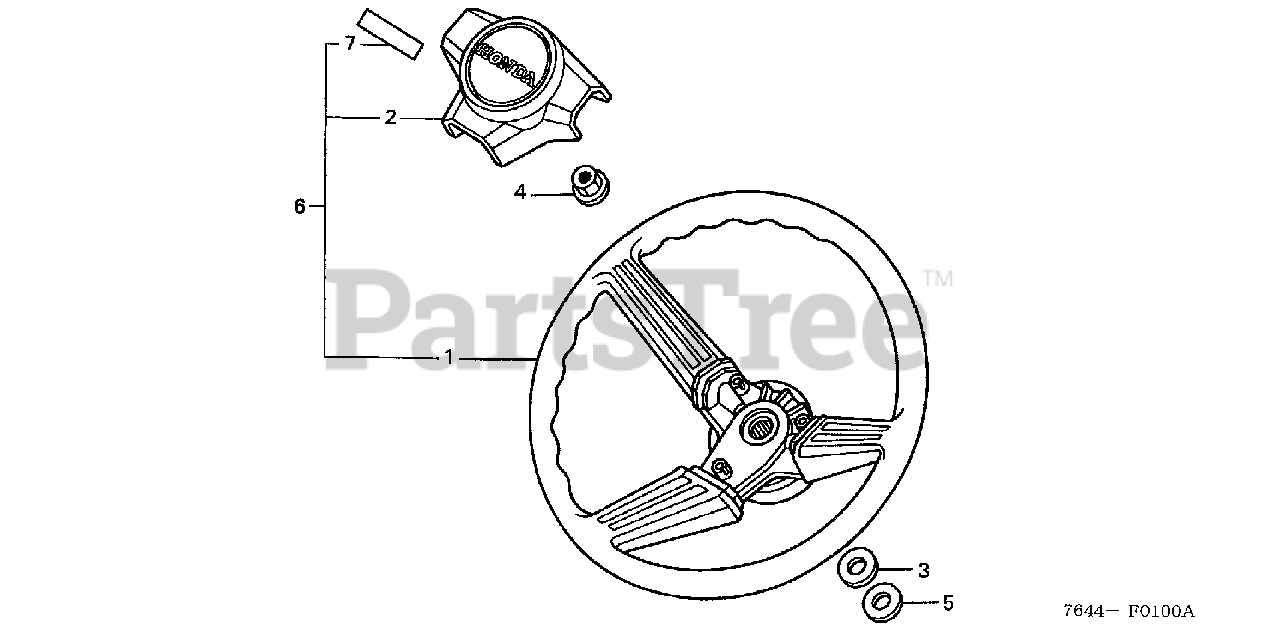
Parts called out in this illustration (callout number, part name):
1	WHEEL, STEERING
2	PAD, CENTER
3	WASHER, STEERING COLUMN
4	NUT, SELF-LOCK
5	WASHER, SPECIAL (18.3MM)
6	WHEEL ASSY., STEERING
7	MARK, EMBLEM (6H000-4149)
